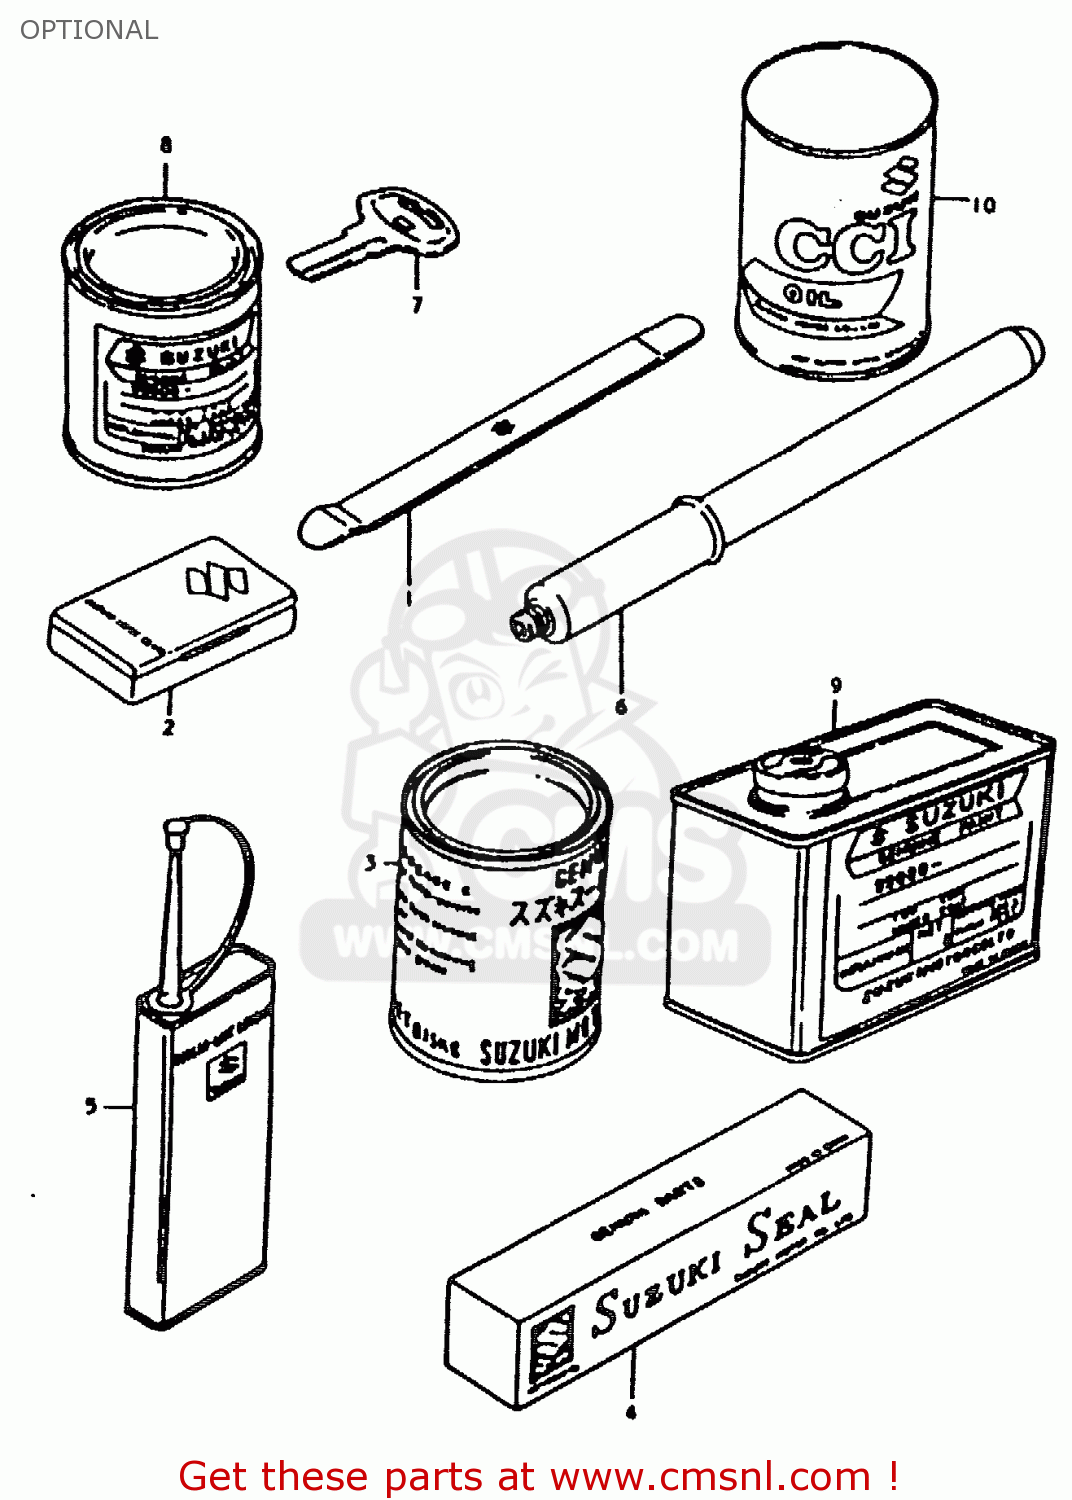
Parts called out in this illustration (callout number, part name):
1	LEVER,TIRE
2	TUBE REPARING TOOL
3	GREASE(C)EP2 LITHIUM 150G
4	GASKET, LIQUID
5	THREAD LOCK NO.1401 CLEAR 200G
6	INFLATOR, AIR
7	KEY,BLANK
8	PAINT,BLACK
9	PAINT (BLACK)
10	CCI OIL
